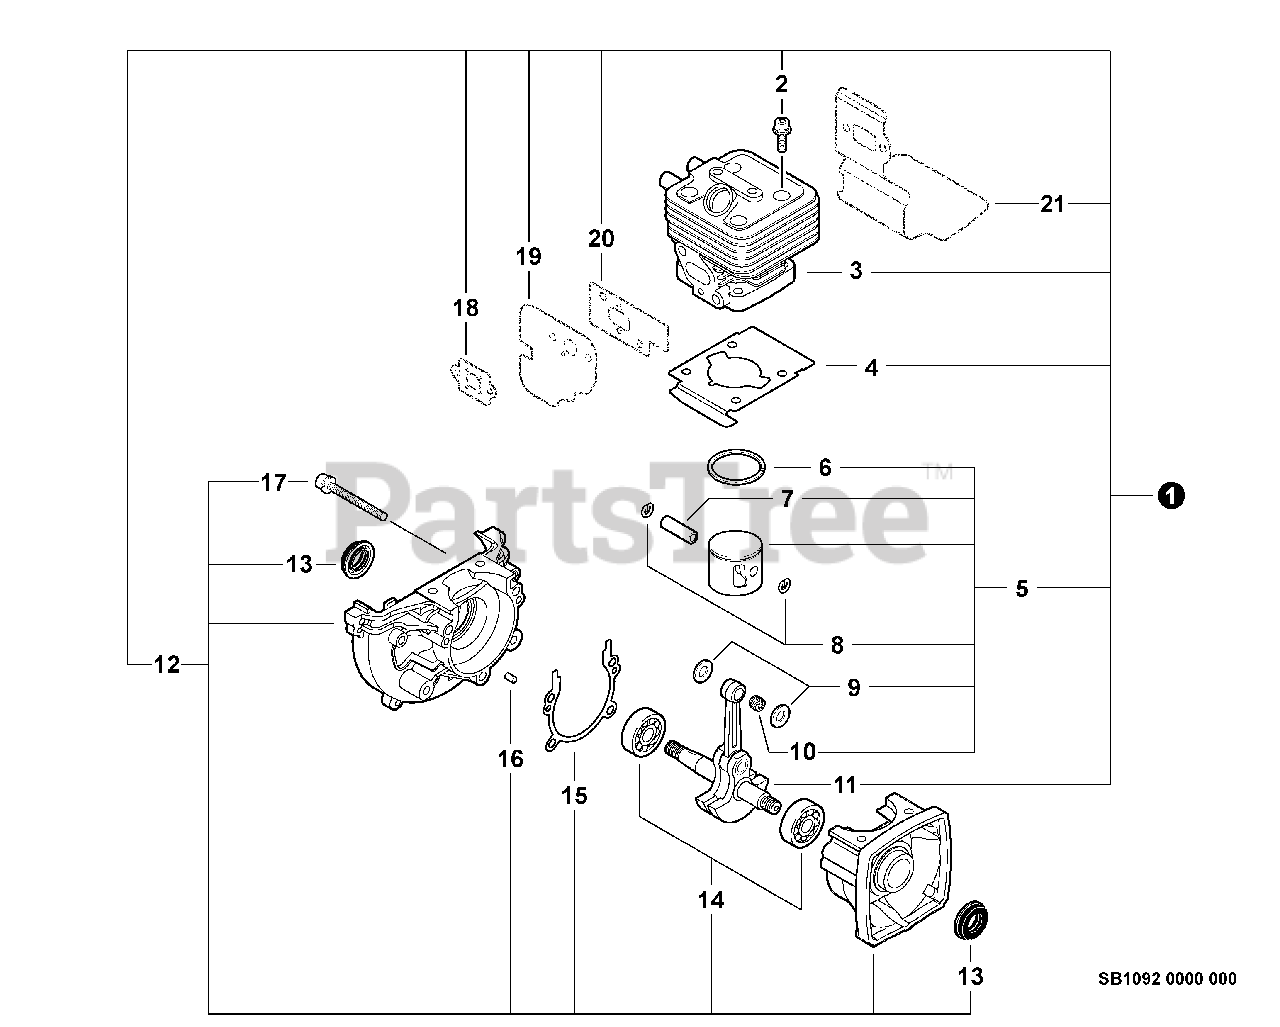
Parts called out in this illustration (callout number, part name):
1	SHORT BLOCK -- SB1092
2	SCREW - 5X25
3	CYLINDER
4	GASKET, CYLINDER
5	PISTON KIT
6	RING, PISTON
7	PIN, PISTON
8	RING, RETAINING
9	SPACER, PISTON
10	BEARING, NEEDLE - 8
11	CRANKSHAFT ASSY
12	CRANKCASE KIT
13	SEAL, OIL
14	BEARING, BALL - 6201
15	GASKET, CRANKCASE
16	PIN - LOCATING
17	SCREW - 5X28
18	GASKET, INTAKE
19	GASKET, INTAKE
20	GASKET, INTAKE
21	SHIELD, EXHAUST
